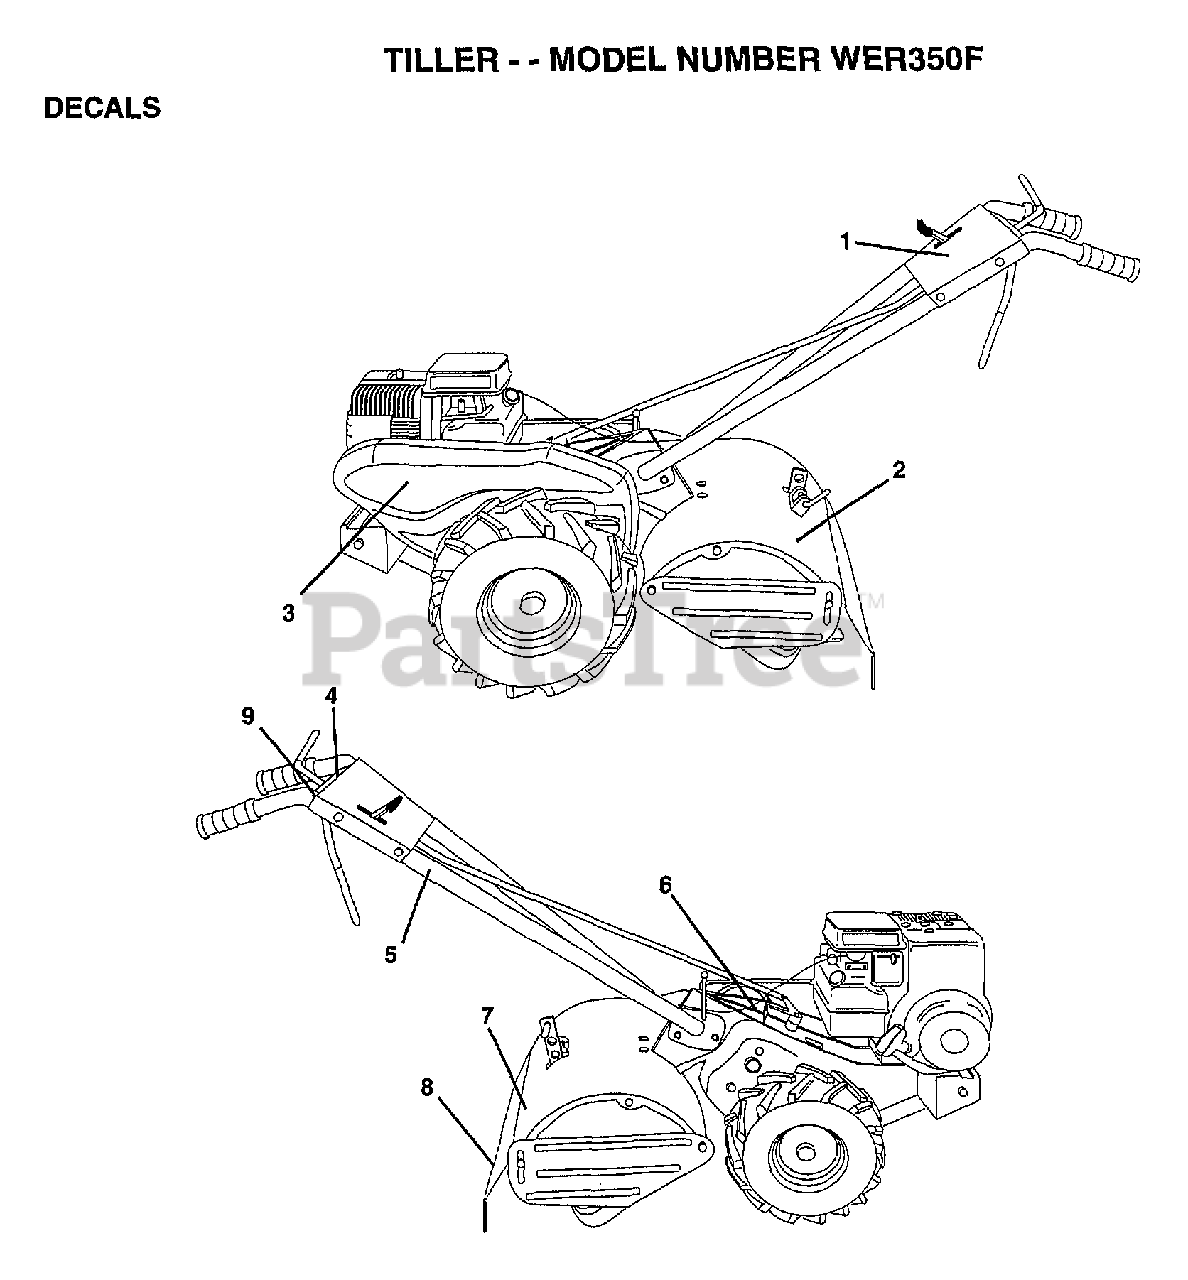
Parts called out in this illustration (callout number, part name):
2	DECAL.DESCRIPTION
3	DECAL, LOGO
5	DECAL TI
6	DECAL CRT
7	DECAL.CAUTION
9	DECAL REVERSE
